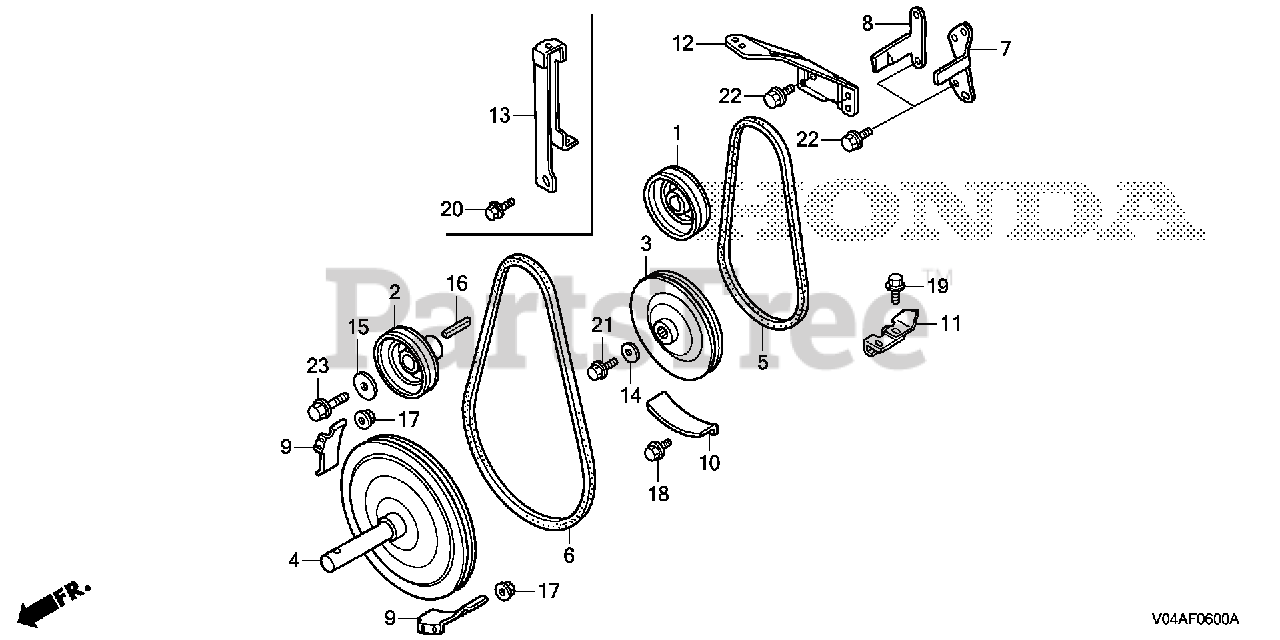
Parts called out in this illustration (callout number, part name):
1	PULLEY, WHEEL DRIVE
2	PULLEY, AUGER DRIVE
3	PULLEY, WHEEL DRIVEN (133MM)
4	PULLEY, AUGER DRIVEN (198MM)
5	V-BELT (SA-27)
6	V-BELT (LB-33)
7	STOPPER, R. BELT (L. SIDE)
8	STOPPER, L. BELT (R. SIDE)
9	STOPPER, AUGER BELT
10	PROTECTOR, BELT (WHEEL)
11	GUIDE, BELT
14	WASHER, CAMSHAFT SIDE
15	WASHER, LOCK (8.5X35X4.5)
17	NUT, FLANGE (6MM)
18	BOLT, FLANGE (6X12)
19	BOLT, FLANGE (6X14)
21	BOLT, FLANGE (6X16)
22	BOLT, FLANGE (8X16)
23	BOLT, FLANGE (8X28)
